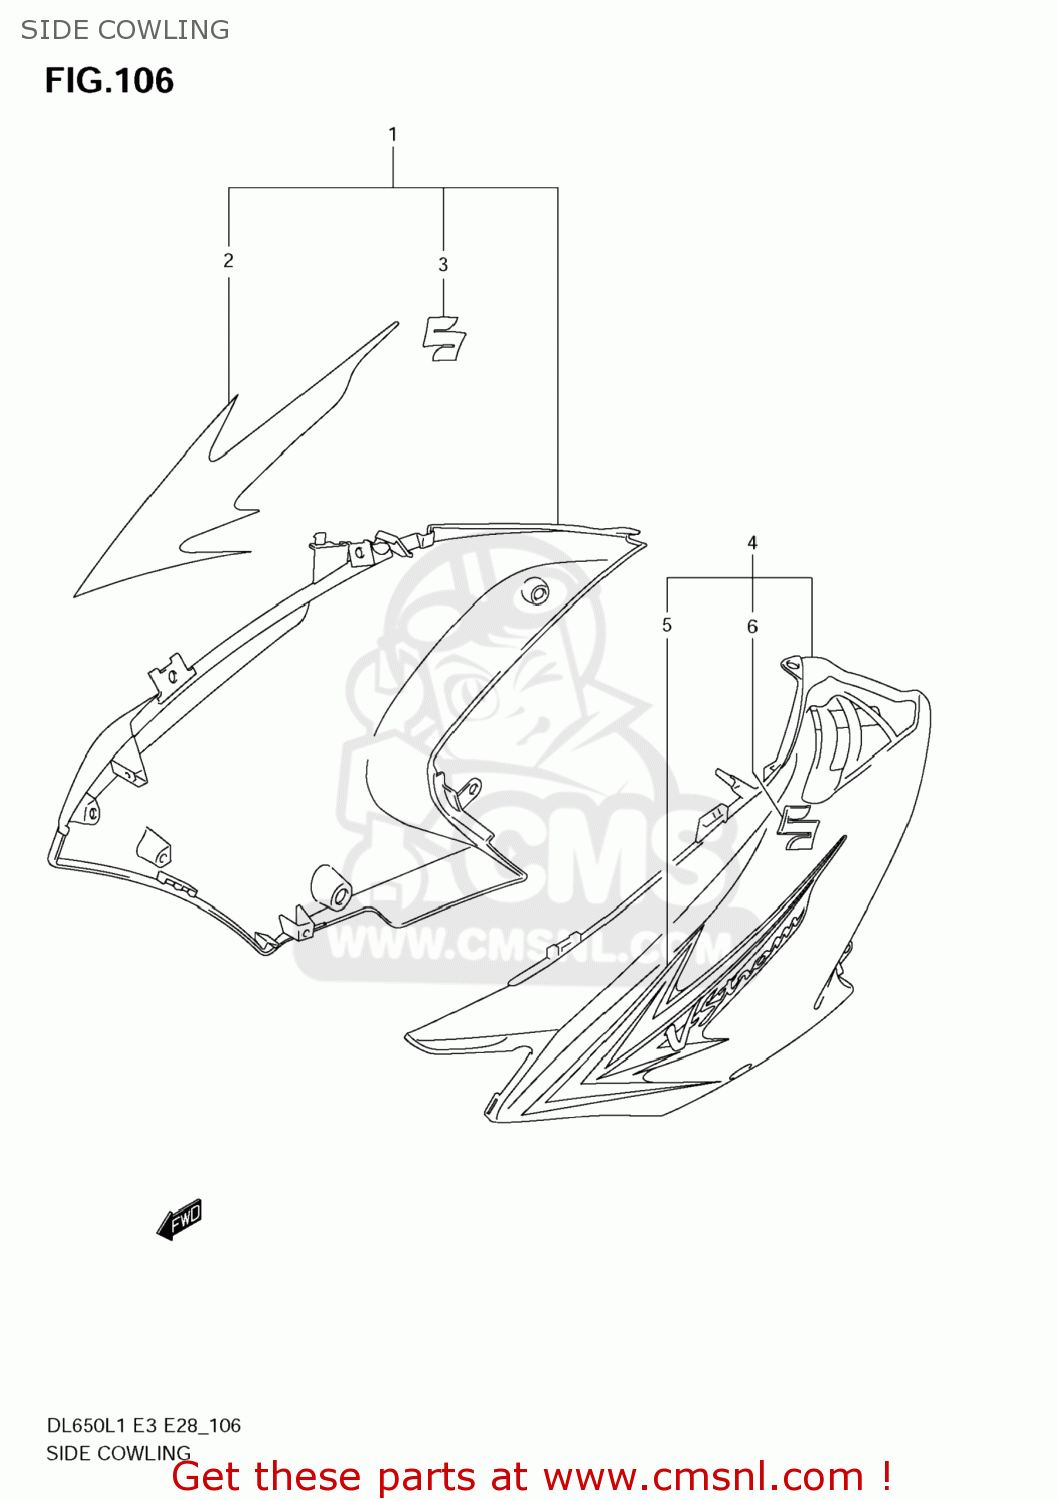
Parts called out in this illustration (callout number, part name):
1	COWLING ASSY,SIDE,R
2	TAPE,COWL SIDE,R
3	EMBLEM,S
4	COWLING ASSY,SIDE,L
5	TAPE,COWL SIDE,L
6	EMBLEM,S
